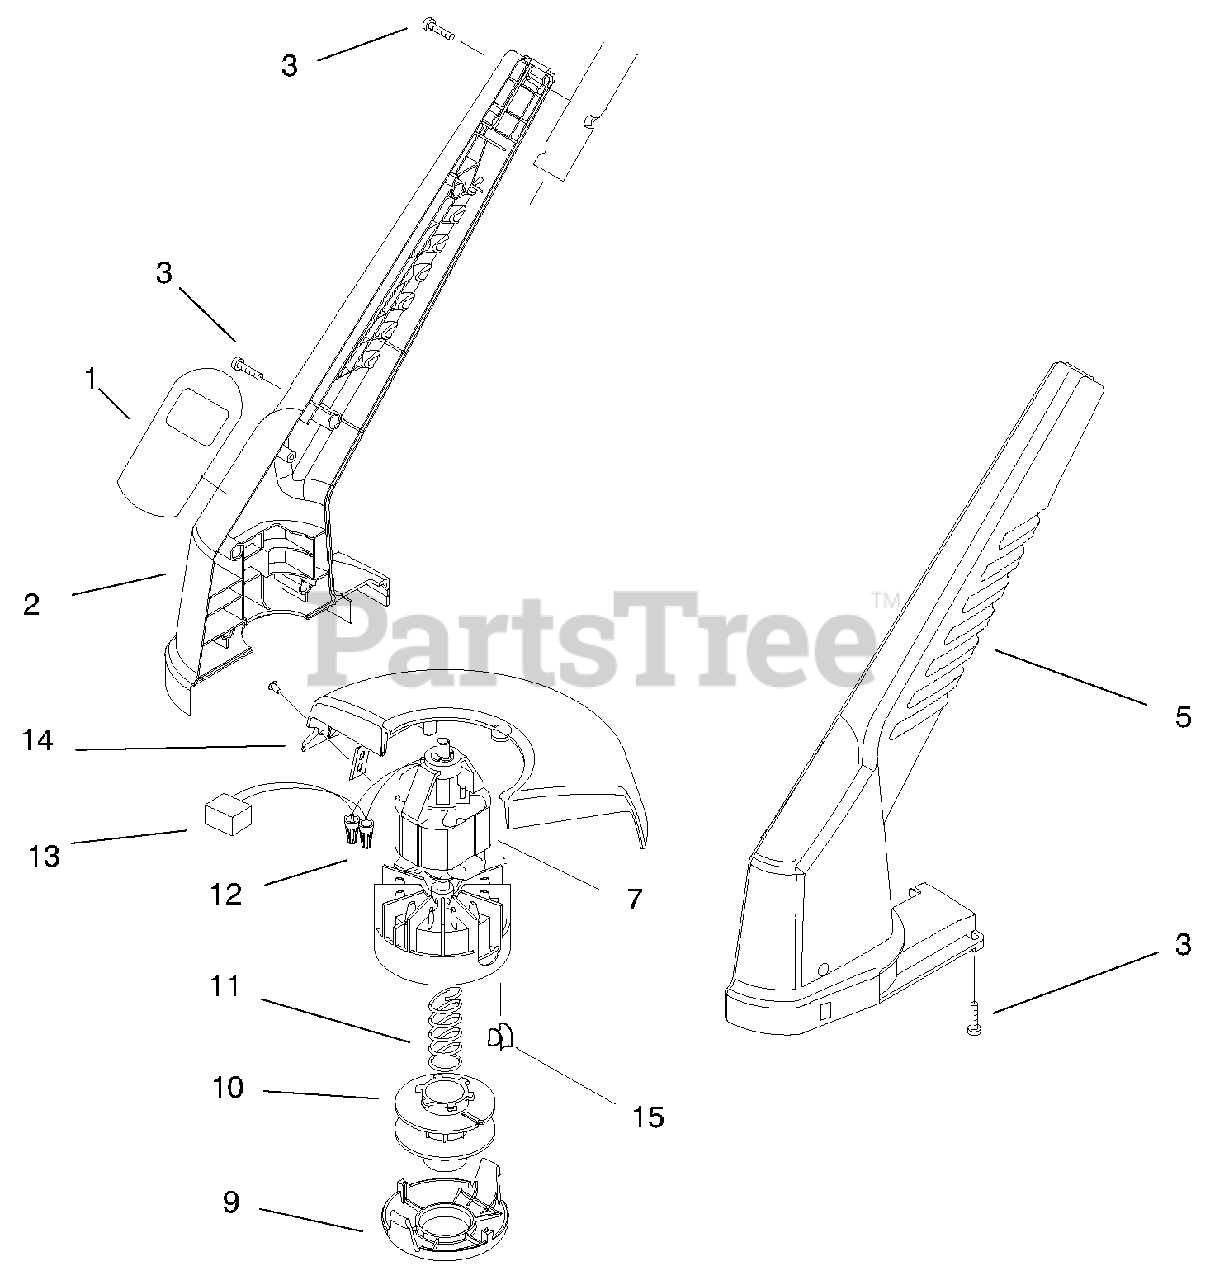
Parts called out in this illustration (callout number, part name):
1	DECAL 25CM TRIMMER
2	Housing R.H.
3	SCREW-PPH
5	Housing L.H.
7	Motor Assembly-Trimmer (Incl. Ref. #15)
10	SPOOL - LARGE
11	SPRING - COMPRESSION
12	CONNECTOR-WIRE NUT
13	FILTER - RFI
14	SHIELD ASM - SERVICE
